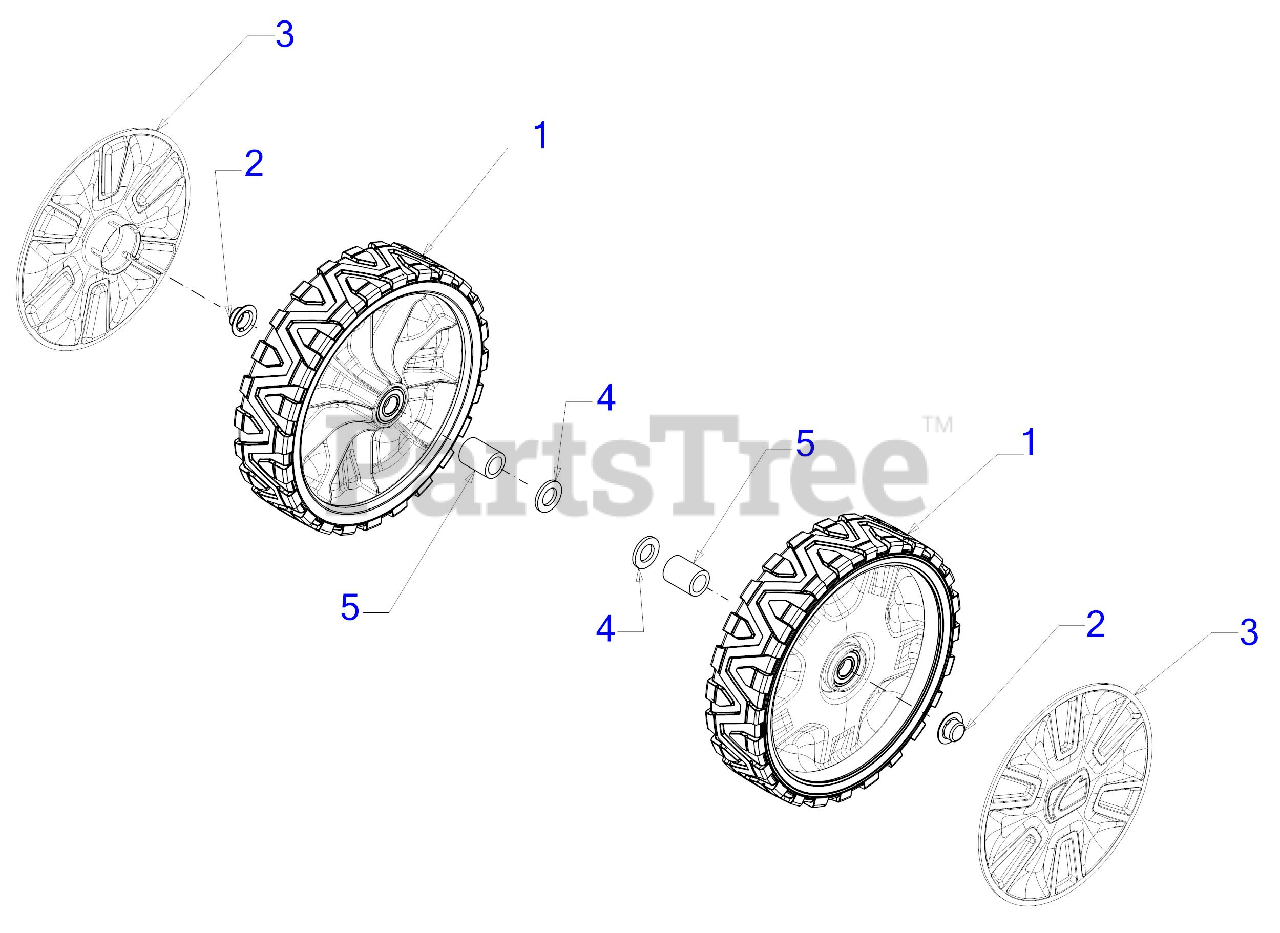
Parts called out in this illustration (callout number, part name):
1	WHEEL ASSEMBLY (8 x 2)
3	HUBCAP-8" CUB
4	FLAT WASHER .535 x .930 x .090
5	SPACER .525 X .775 X 1.015
